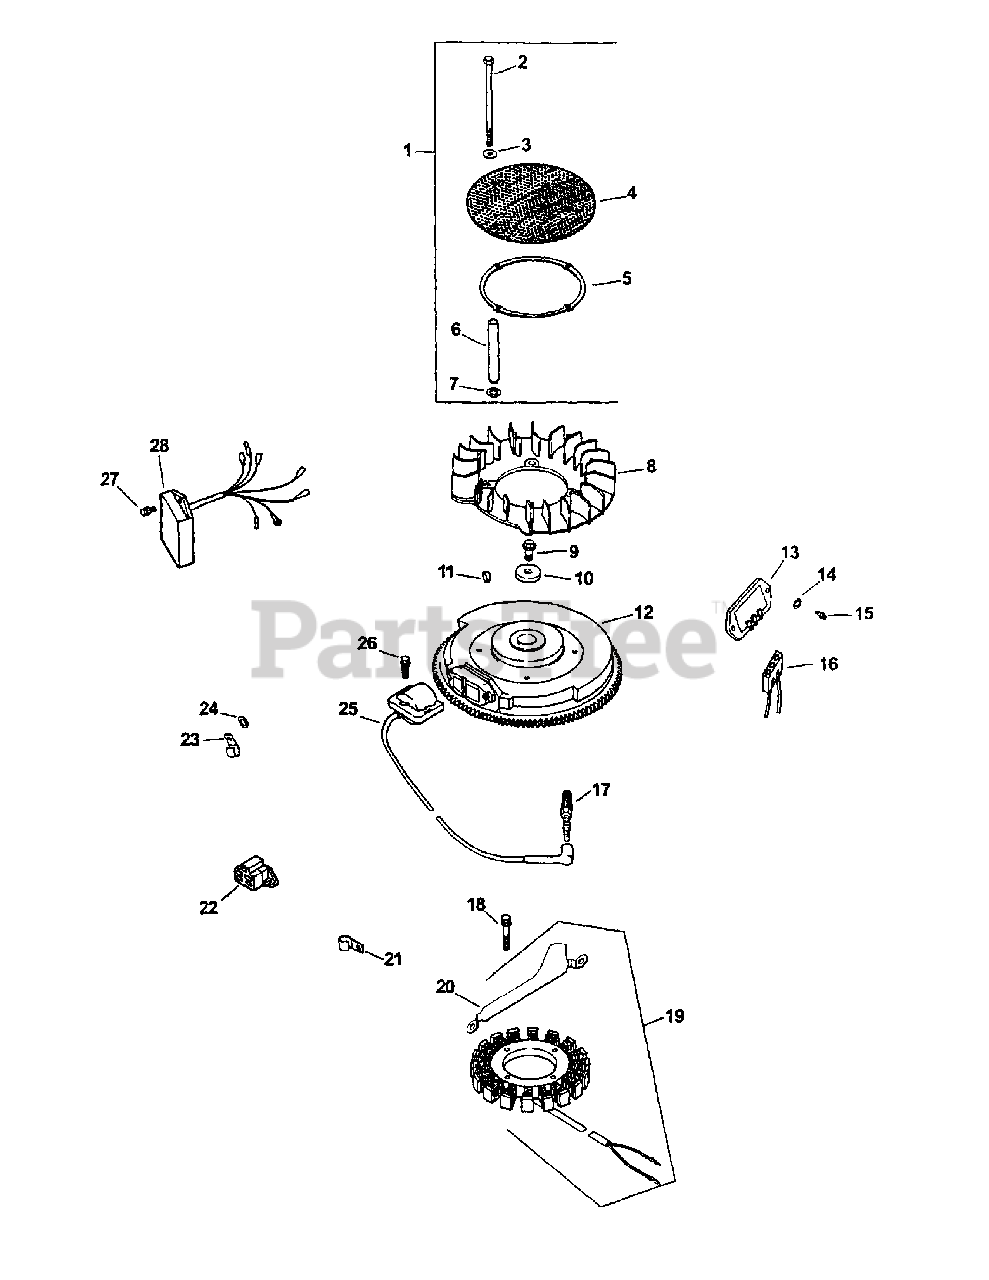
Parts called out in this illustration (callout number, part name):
1	Kit, Chopper Screen
2	Screw, Hex Cap
3	Washer, Plain 1/4"
4	Screen, Grass
5	Ring, Support
6	Spacer, Grass Screen
7	Washer, Spring 10 mm
8	Fan
9	Screw, Hex Flange
10	Washer, Plain 3/8"
13	Rectifier - Regulator
14	Washer, Plain 3/16"
15	Screw, Phillips Head 11-16 x 7/8
16	Connector (3 Contact)
17	Spark Plug
18	Screw, I-lex Cap
19	Kit, 15 Amp Stator
20	Bracket, Stator Wire
21	Clip, Cable
22	Connector (5 Contact)
23	Clip, Cable
24	Washer, Plain 1/4"
25	Module, Ignition
26	Screw, Thread forming
27	Screw, Hex Flange
28	Module, Speed Advance
